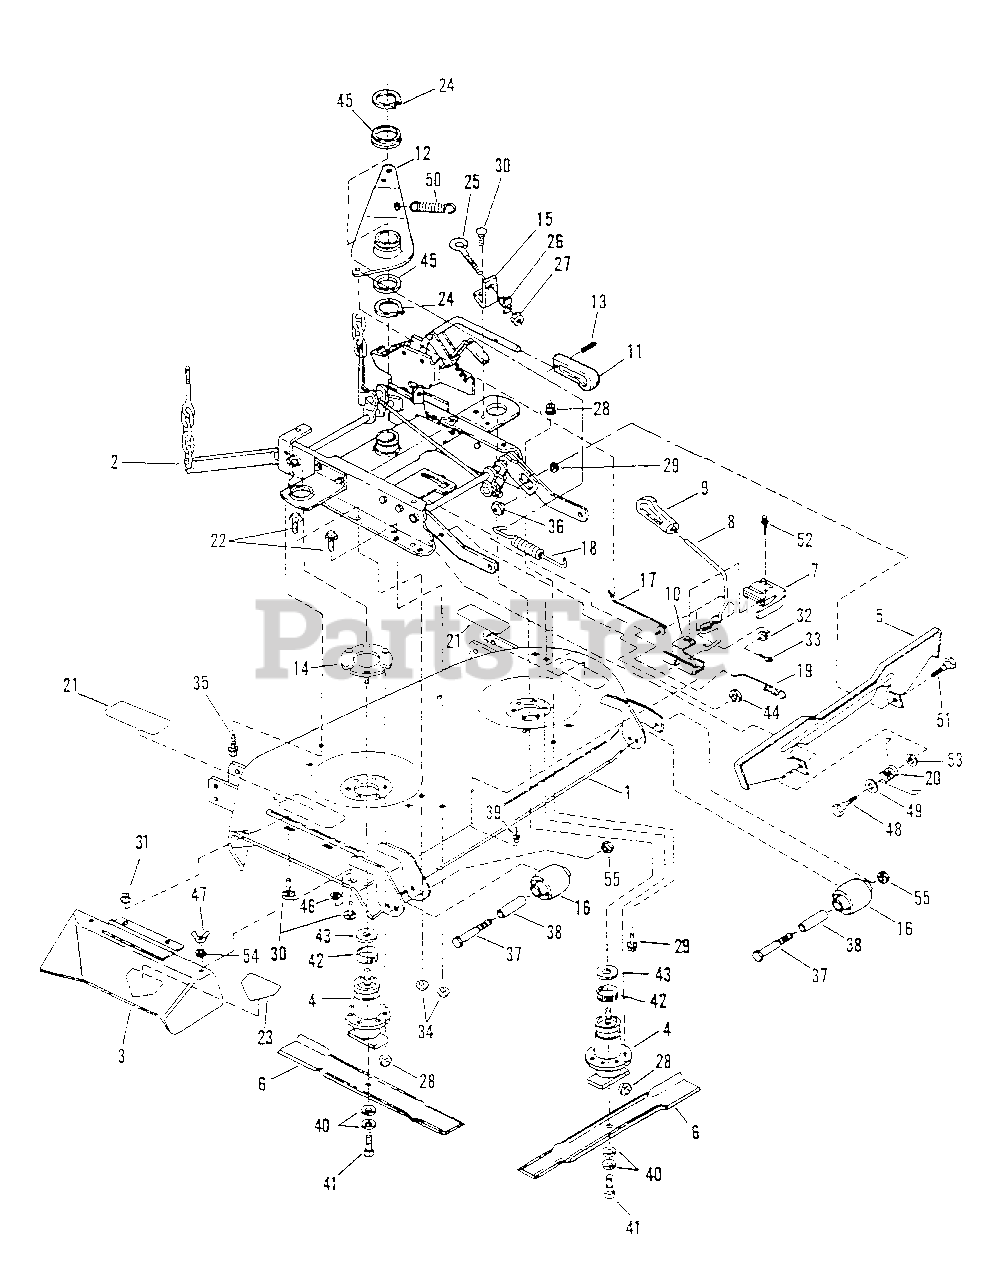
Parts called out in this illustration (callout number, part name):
1	ASSEMBLY, Deck
2	ASSEMBLY, Rail
3	ASSEMBLY, Side Chute
4	ASSEMBLY, Spindle
5	ASSEMBLY, Pedal
6	21" BLADE
7	SWITCH, Deck Interlock
8	LEVER, Blade Engagement
9	GRIP, Handle
10	MOUNT, Handle
11	GRIP, Height Adjustment Lever
12	ARM, Idler
13	PIN, 3/16 x 3/4" Roll
14	ASSEMBLY, Spindle Ring
15	ANCHOR
16	ROLLER
17	ROD, Idler
18	SPRING, Belt
19	SPRING, Latch
20	SPRING, Pedal
21	DECAL, Caution
22	BOLT, 5/16-18 x 5/8" Hex Flange Lock
23	DECAL, Danger
24	RING, 2" External Retaining
25	BOLT, 1/4-20 Eye
26	T-NUT, 1/4-20
27	NUT, 1/4-20 Hex
28	NUT, 3/8-16 Hex Lock
29	WASHER, 3/8 Internal Tooth Lock
30	BOLT, 5/16-18 x 3/4" Carriage
31	NUT, 5/16-18 Hex Flange Lock
32	WASHER, 1/4 Flat
33	PIN, 3/32 x 3/4" Cotter
34	NUT, 5/16-18 Hex Flange Lock
35	SCREW, 5/16-18 x 5/8" Self-Tapping
36	ECCENTRIC, Leveling
37	SCREW, 3/8-24 x 3-3/4" Hex Head Cap
38	SPACER
39	SCREW, 1/4-20 x 5/8" Self-Tapping
40	WASHER, Cone
41	SCREW, 3/8-24 x 1" Hex Head Cap
42	RING, Tolerance
44	NUT, 3/8-24 Hex Lock
45	WASHER, 2" I.D. Nylon
46	RETAINER,5/16 Bolt
47	NUT, 5/16-18 Wing
48	BOLT, 3/8-24 x 9/16" Shoulder
49	WASHER, 1/2 Flat
50	SPRING, Return
51	BOLT, 3/8-24 x 3/4" Shoulder
52	SCREW, #10-32 x 1" Self-Tapping
53	WASHER, 3/8" Flat
54	WASHER, 5/16 Flat
55	NUT, 3/8-24 Hex Lock (Nyloc)
